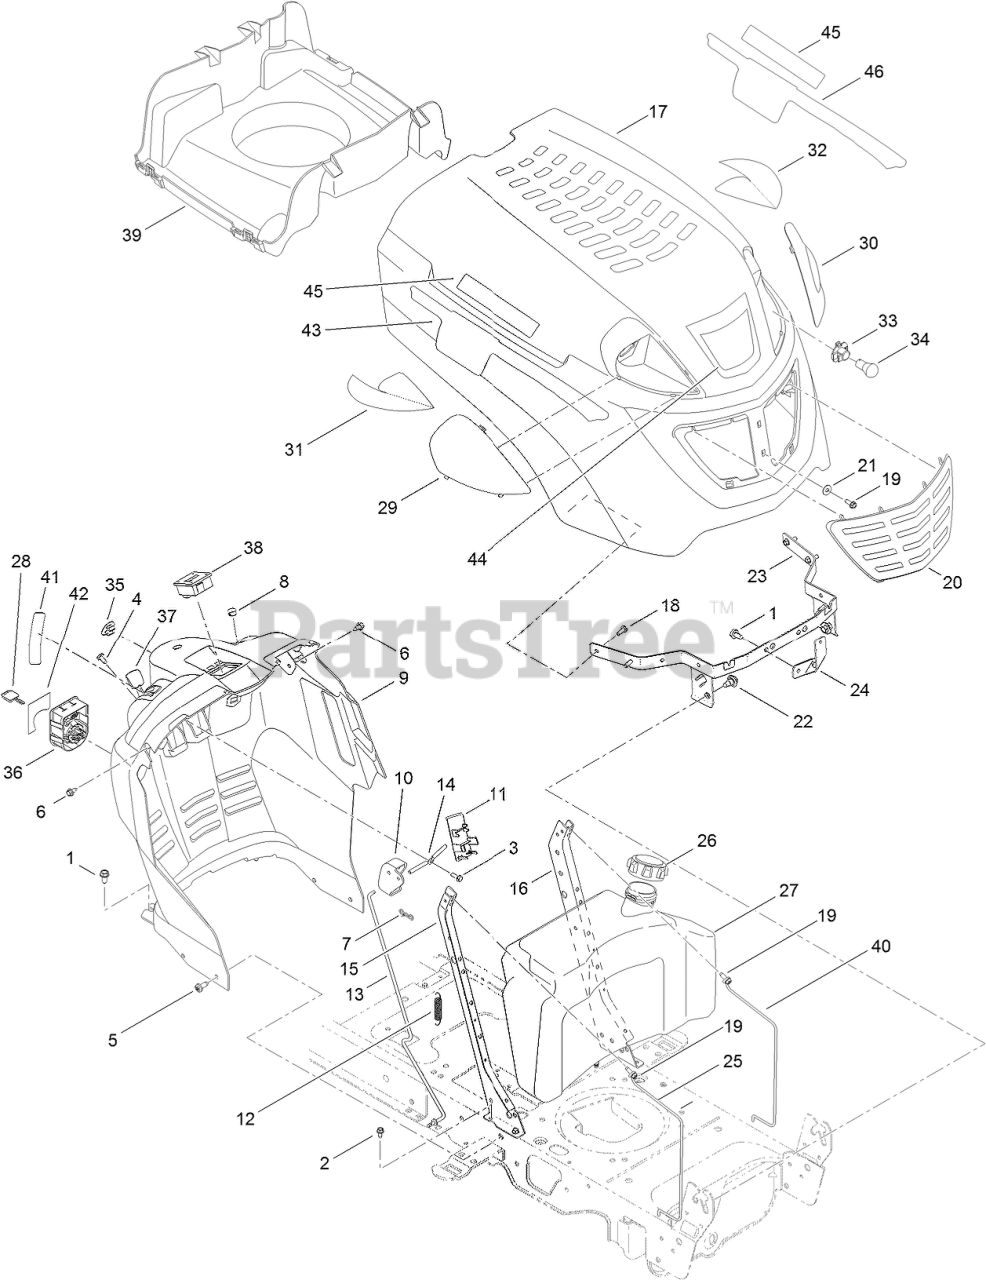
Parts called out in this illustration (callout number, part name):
1	SCREW-TAP
2	SCREW-HWHTF
3	SCREW-TAP
4	SCREW-TAP
5	SCREW-TAP
6	SCREW-HWH
7	PIN-COTTER
8	CAP-PLUG, HOLE
9	DASH-MANUAL, PTO
10	LEVER-DASH
11	COVER-CRUISE
12	SPRING-EXTENSION
13	ROD-LATCH
14	ROD-LEVER, BENT
15	SUPPORT-DASH, PLATE (RH)
16	SUPPORT-DASH, PLATE (LH)
19	SCREW-TAP
21	WASHER-FLAT
22	BOLT-SHOULDER, TAP
23	BRACKET-PIVOT
24	BRACKET-SUPPORT, HOOD
25	ROD-SUPPORT
26	CAP-FUEL
27	TANK-FUEL
28	KEY-IGNITION
29	LENS-RH
30	LENS-LH
31	REFLECTOR-RH
32	REFLECTOR-LH
33	SOCKET-HEADLIGHT
34	LAMP-12V, MINIATURE
35	PLUG-CHOKE
36	MODULE-SWITCH, IGNITION
37	CABLE-THROTTLE/CHOKE
38	METER-HOUR
39	PLENIUM-HOOD
40	ROD-SUPPORT, LH TANK
41	DECAL-THROTTLE
42	DECAL-SWITCH, IGNITION
43	DECAL-HOOD, RIGHT SIDE
44	DECAL-HOOD
46	DECAL-HOOD, LEFT SIDE
